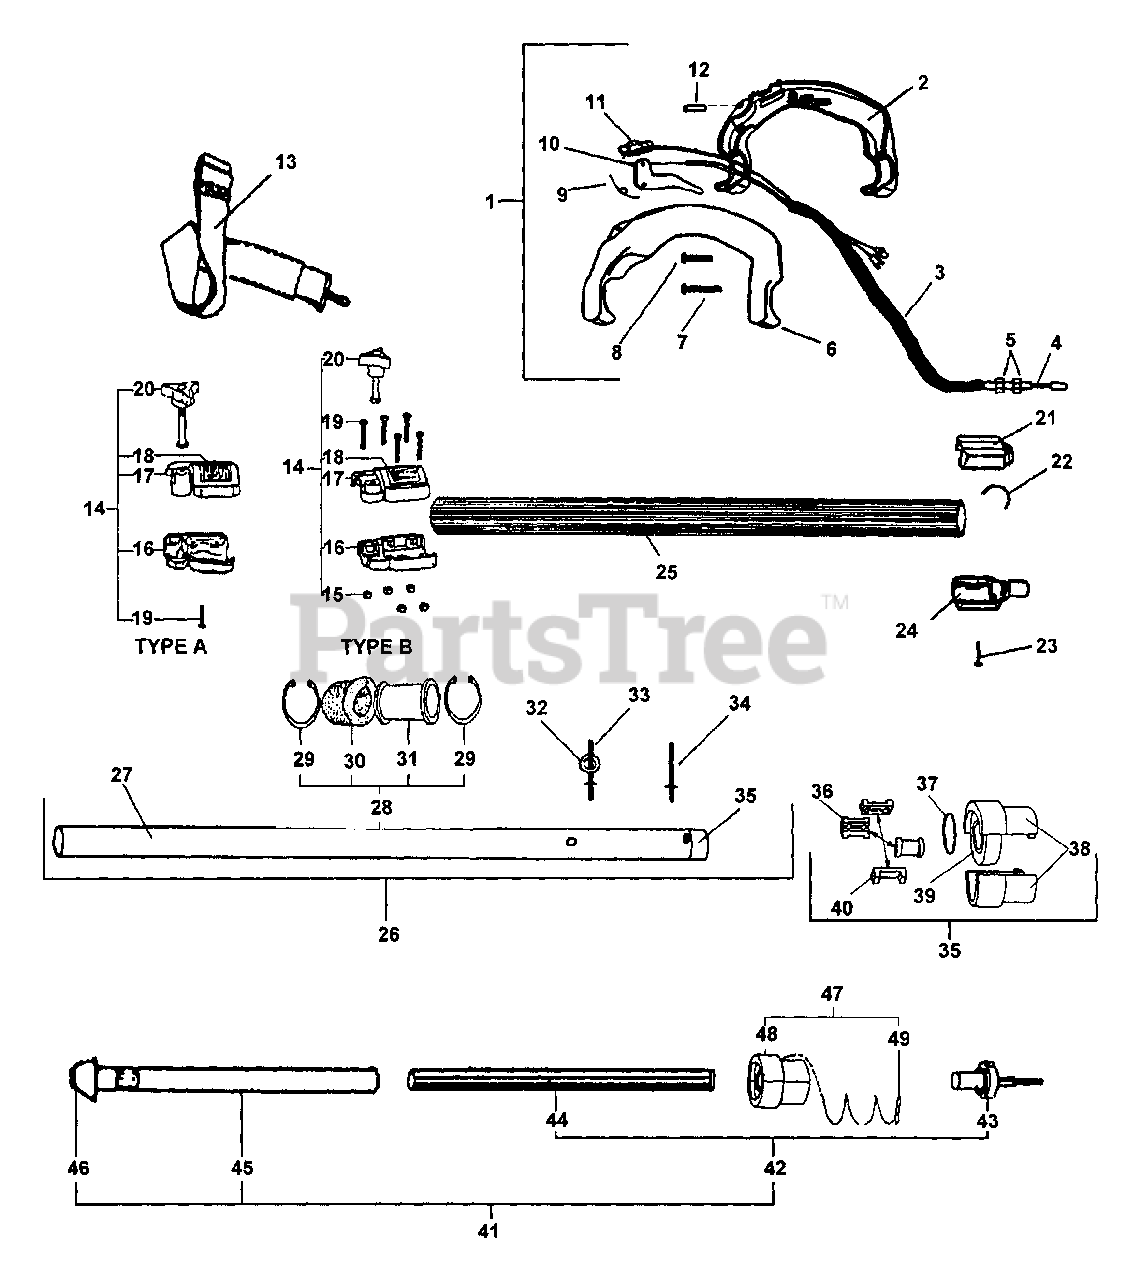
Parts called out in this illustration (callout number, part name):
1	HANDLE ASSY - REAR
2	HANDLE, REAR - RIGHT
3	TUBE, PROTECTIVE - CORRUGATED
4	CABLE, THROTTLE
6	HANDLE, REAR - LEFT
7	SCREW - 10-24 X 1-1/4"
8	SCREW - 10-24 X 7/8"
9	SPRING, TRIGGER
10	TRIGGER, THROTTLE
11	IGNITION SWITCH ASSY
12	PIN - LOCATING
13	SHOULDER STRAP ASSY
14	COLLAR ASSY
15	LOCKNUT - 10-24
16	COLLAR, MAIN PIPE - LOWER
17	COLLAR, MAIN PIPE - UPPER
18	LABEL - CAUTION
19	SCREW - 10-24 X 1-1/4"
20	THUMBSCREW
21	LOWER HSNG ADAPT (TOP)
23	SCREW - 10-24 X 1-1/4"
24	ADAPTER - LOWER
25	PIPE, MAIN - ORANGE
26	MAIN PIPE ASSY
27	PIPE, MAIN - BLACK
28	DRIVESHAFT GUIDE ASSY
29	RING, RETAINING
30	PAD, FOAM
31	GUIDE, DRIVESHAFT
32	WASHER - 5
35	BEARING HOLDER KIT
36	HOLDER, INNER BEARING - SMALL
37	WASHER - SPRING
38	BEARING HOLDER KIT
39	BEARING, BALL - 6002
40	HOLDER, INNER BEARING - LARGE
41	DRIVESHAFT ASSY
42	DRIVESHAFT - LOWER
43	CONNECTOR, SHAFT
44	DRIVESHAFT - LOWER
45	DRIVESHAFT - UPPER
46	ADAPTER, DRIVESHAFT - UPPER
47	FLOATING BUSHING ASSY
49	BUSHING, FLOATING
